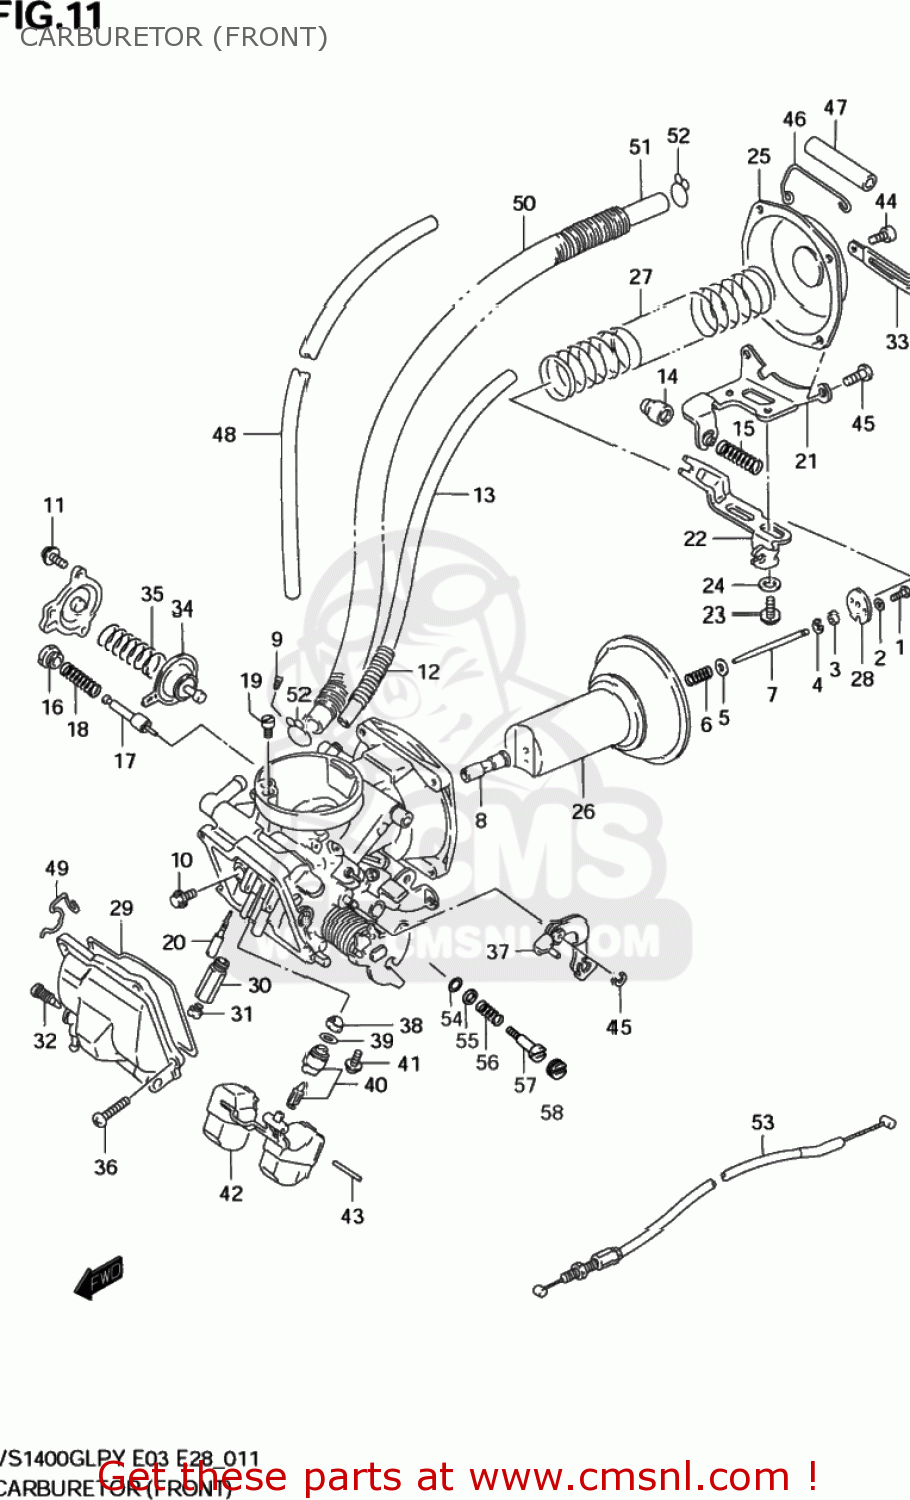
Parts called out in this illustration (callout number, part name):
1	SCREW
2	WASHER,LOCK
3	RING
4	CLIP
5	WASHER
6	SPRING
7	NEEDLE,JET
8	JET,NEEDLE(O-9)
9	JET,AIR
10	SCREW
11	SCREW
12	SPRING
13	HOSE(5X8.2X600)
14	CAP
15	SPRING
16	HOLDER,GUIDE
17	PLUNGER
18	SPRING
19	JET,PILOT
20	JET,PILOT(50)
21	BRACKET
22	PLATE
23	SCREW
24	WASHER
25	COVER,DIAPHRAGM
26	DIAPHRAGM ASSY
27	SPRING,DIAPHRAGM
28	PLATE
29	O RING,FLOAT CHAMBER
30	HOLDER,MAIN JET
31	JET,MAIN(125)
32	PLUG,DRAIN
33	CLAMP
34	DIAPHRAGM ASSY
35	SPRING
36	SCREW
37	LEVER ASSY
38	FILTER
39	O-RING,NEEDLE VALVE
40	VALVE ASSY,NEEDLE
41	SCREW
42	FLOAT
43	PIN,FLOAT
44	SCREW
45	E RING
46	CLIP
47	HOSE(6X10X600)
48	(CA) HOSE SET,FUEL
49	CLAMP
50	SHIELD,HEAT FUEL HOSE
51	HOSE(6.5X11.5X600)
52	CLIP
53	CABLE,IDLE SYNCRO
54	O RING,PILOT AIR SCREW
55	WASHER
56	SPRING
57	SCREW,PILOT
58	PLUG
